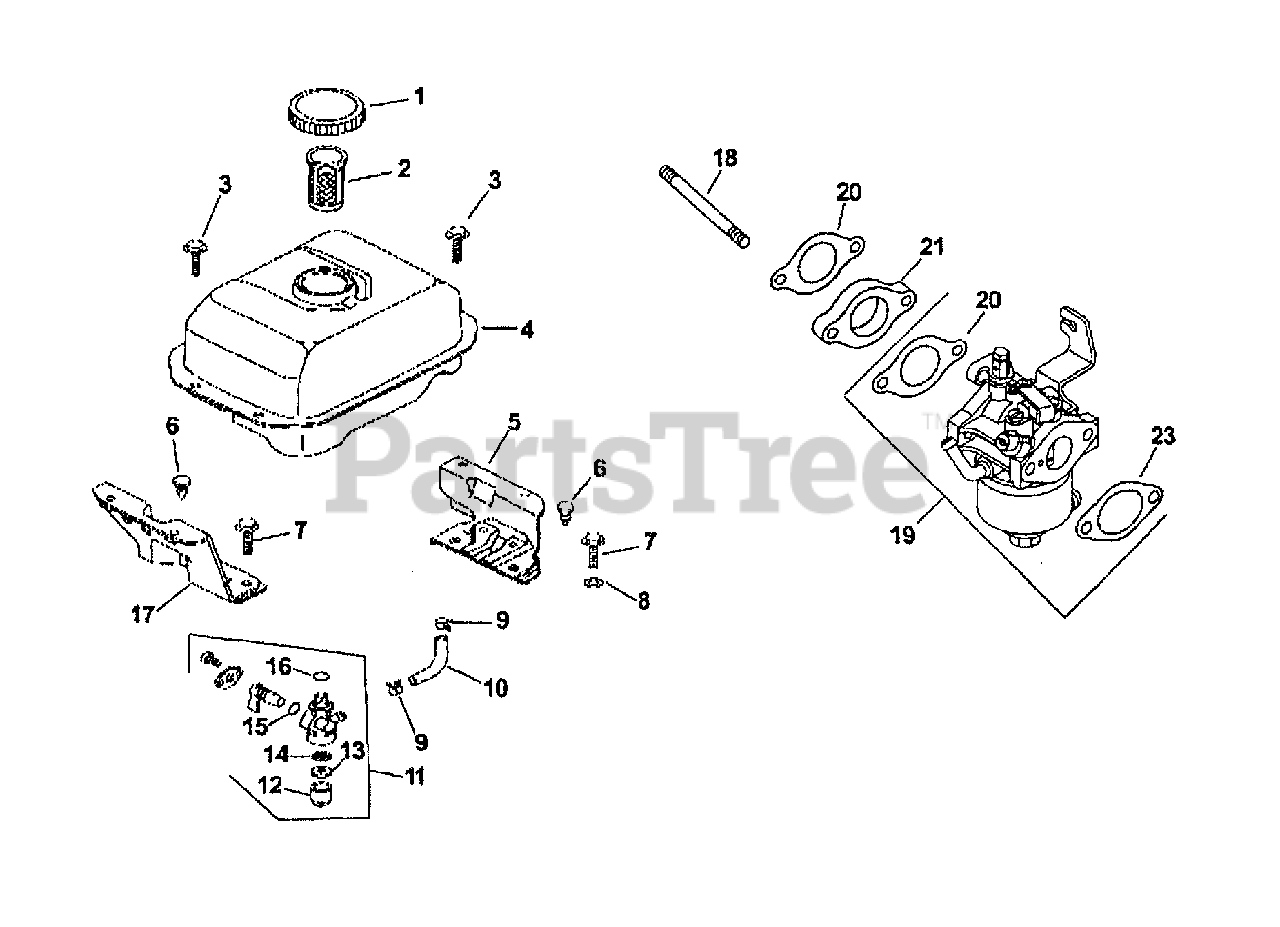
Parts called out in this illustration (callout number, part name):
1	Cap, Fuel Tank
5	Bracket, Fuel Tank
14	Filter, Screen
17	Bracket, Fuel Tank
18	Stud, Carburetor
19	Kit, Carburetor
20	Gasket, Intake
21	Manifold, Intake
23	Gasket, Air Cleaner
